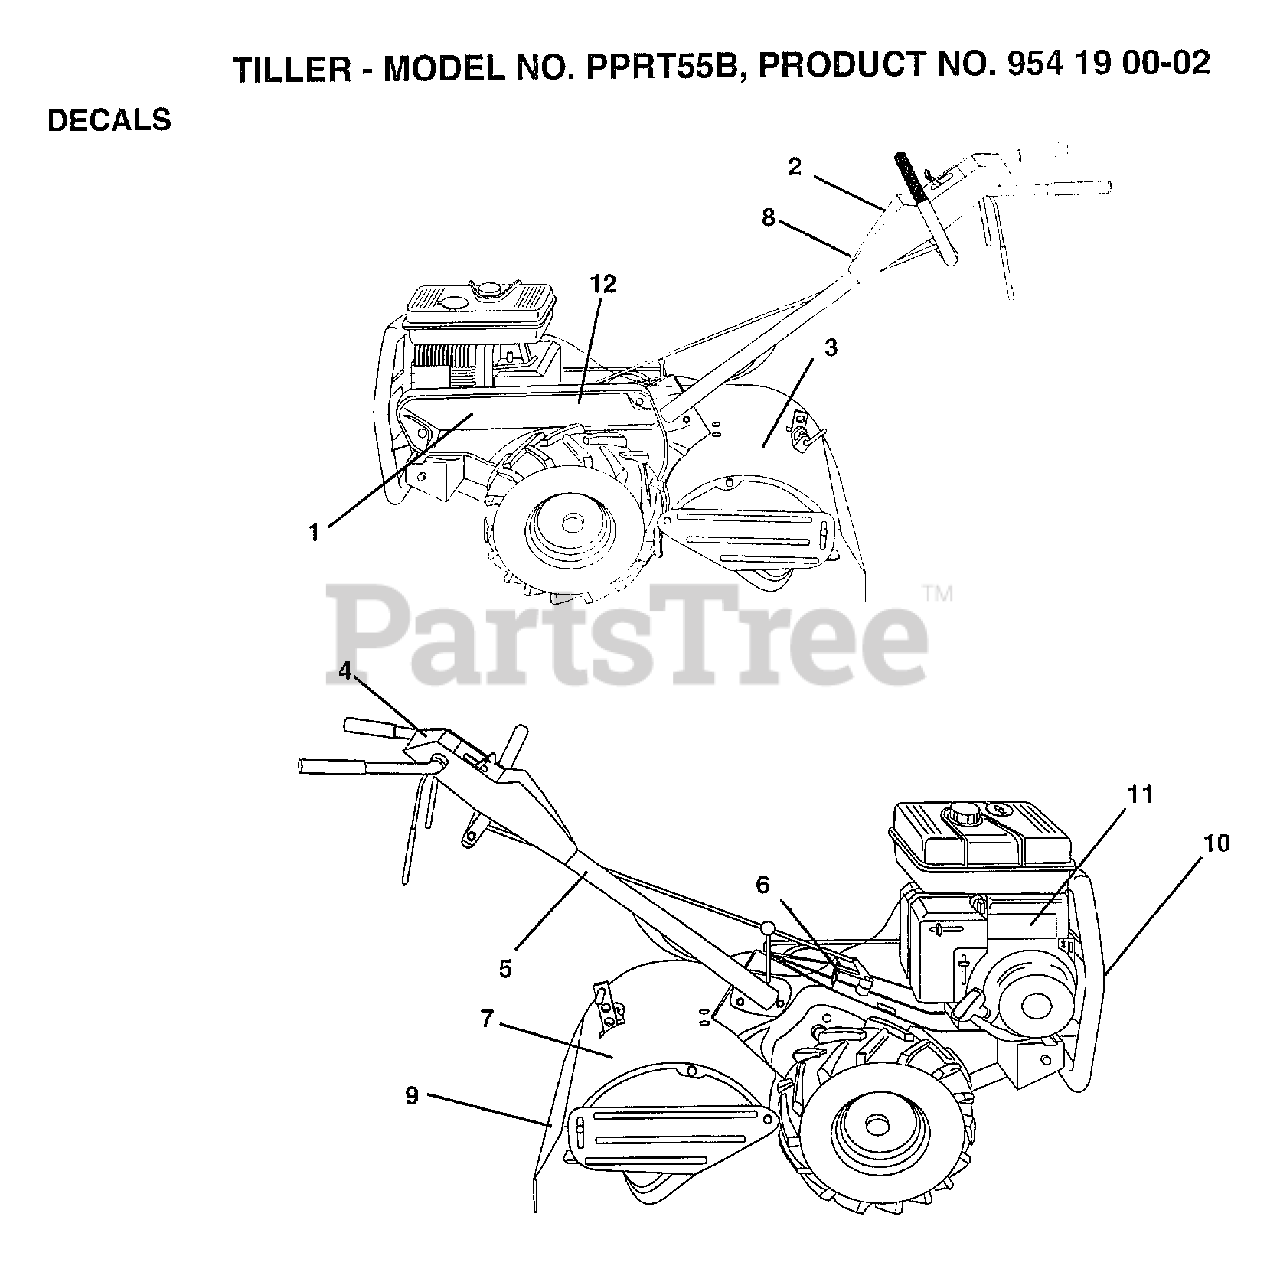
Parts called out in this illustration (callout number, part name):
1	DECAL, LOGO
2	DECAL.FENDER.BELT.GUARD
3	DECAL, LOGO
4	DECAL.INSTRUCTION
5	DECAL TI
6	DECAL CRT
7	DECAL.CAUTION
8	DECAL.CTRL.PANEL.5.5HP
9	DECAL WARNING ROTATING TINES
10	DECAL, BUMPER/GRILLE
11	DECAL, ENGINE PRED.
12	RETAINER-SPRING
